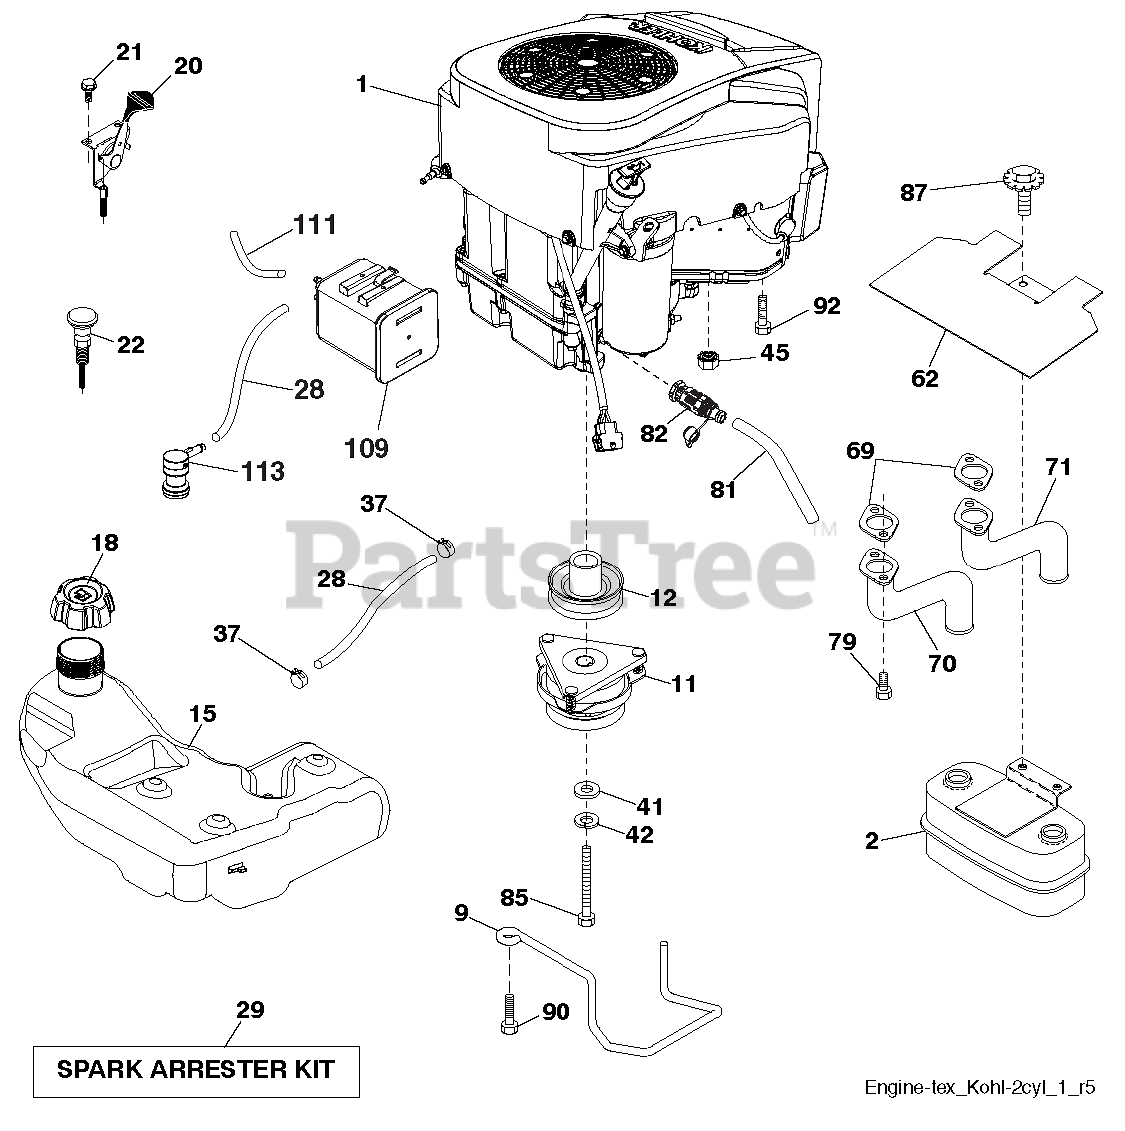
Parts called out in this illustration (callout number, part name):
2	MUFFLER.ASM.TWN.EXTNDED.DFLCTR
9	KEEPER.BELT.ENGINE.4.2
11	CLUTCH.ELECTRIC.LT.48"*
12	PULLEY.ENGINE.TUFFTORQ
15	TANK.ASM.FUEL.3GA.CARB
18	CAP.ASM.FL.RITCH.3"E10.SYM.498
20	THROTTLE CONTROL
21	SCREW.#10 X 0.750.BOS
22	CONTROL.CHOKE.ERGO.PUSH-IN.BLA
28	LINE.FUEL.64"REAR.EMIS
29	KIT.SPARK ARRESTOR 794945 B&S
37	HOSE CLAMP
42	LOCKWASHER
45	NUT
62	SHIELD.HEAT.MUFFLER
69	GASKET.EXHAUST.KOHL.CV18-CV26
70	RP.PIPE-EXHAUST LH
71	RP.PIPE-EXHAUST RH
79	SCREW.SOCKET HD.5/16-1
81	TUBE, DRAIN OIL ASM.
82	VALUE.OIL.DRAIN
85	BOLT HEX 7/16-20X4-1/4"
87	BOLT.5/16-18UNCX3/4 W/SEMS.BLK
90	SCREW 3/8-16X1
92	SCREW 3/8-16X1
109	CANNISTER, CARBON
111	PURGE.LINE.36"REAR.CALIFORNIA
113	VALVE.SLANT.CARTRDG.90 DEG.TEX
